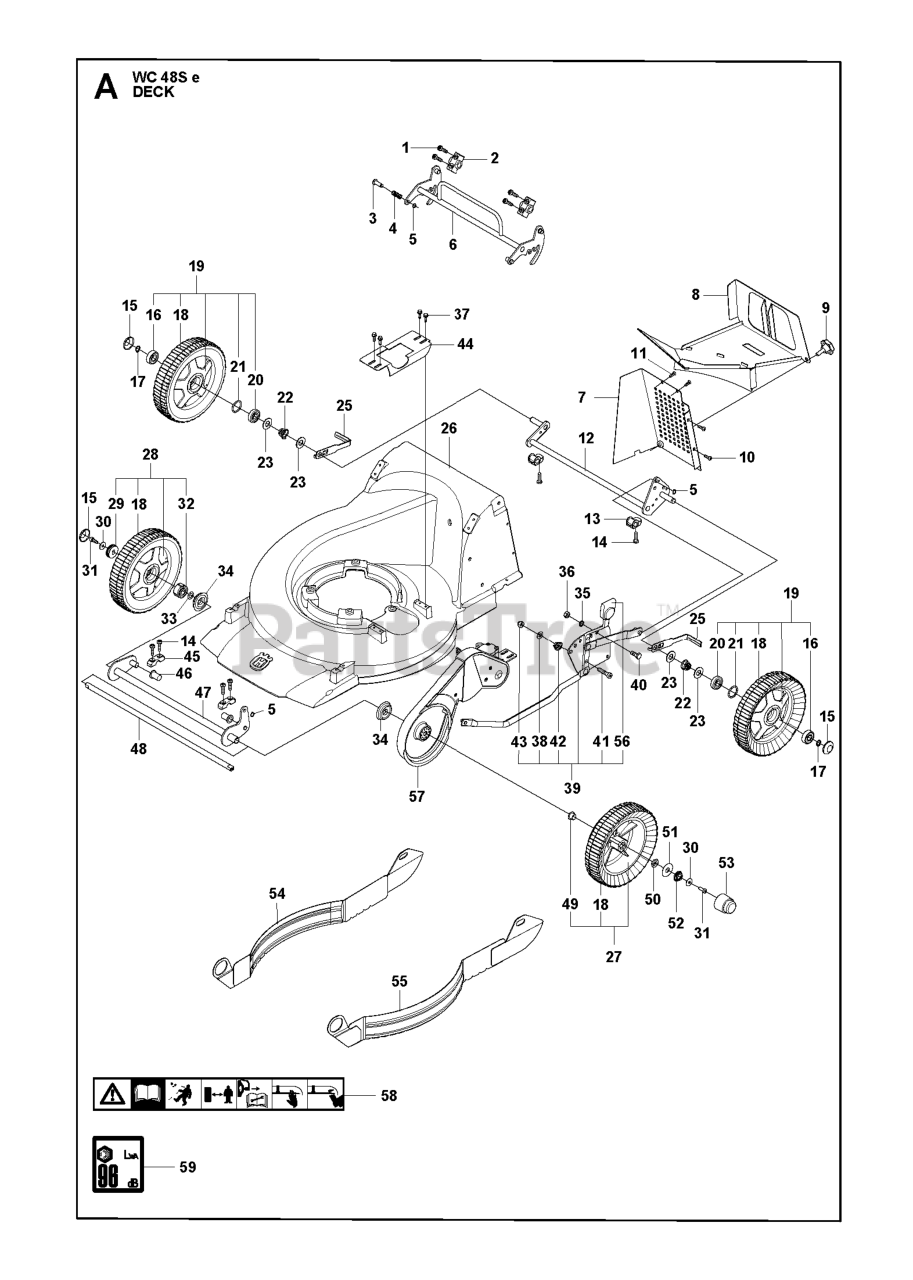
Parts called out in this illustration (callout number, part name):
5	RETAINING RING SGA 8
36	NUT
43	NUT LOCK - M8, NYLOCK
